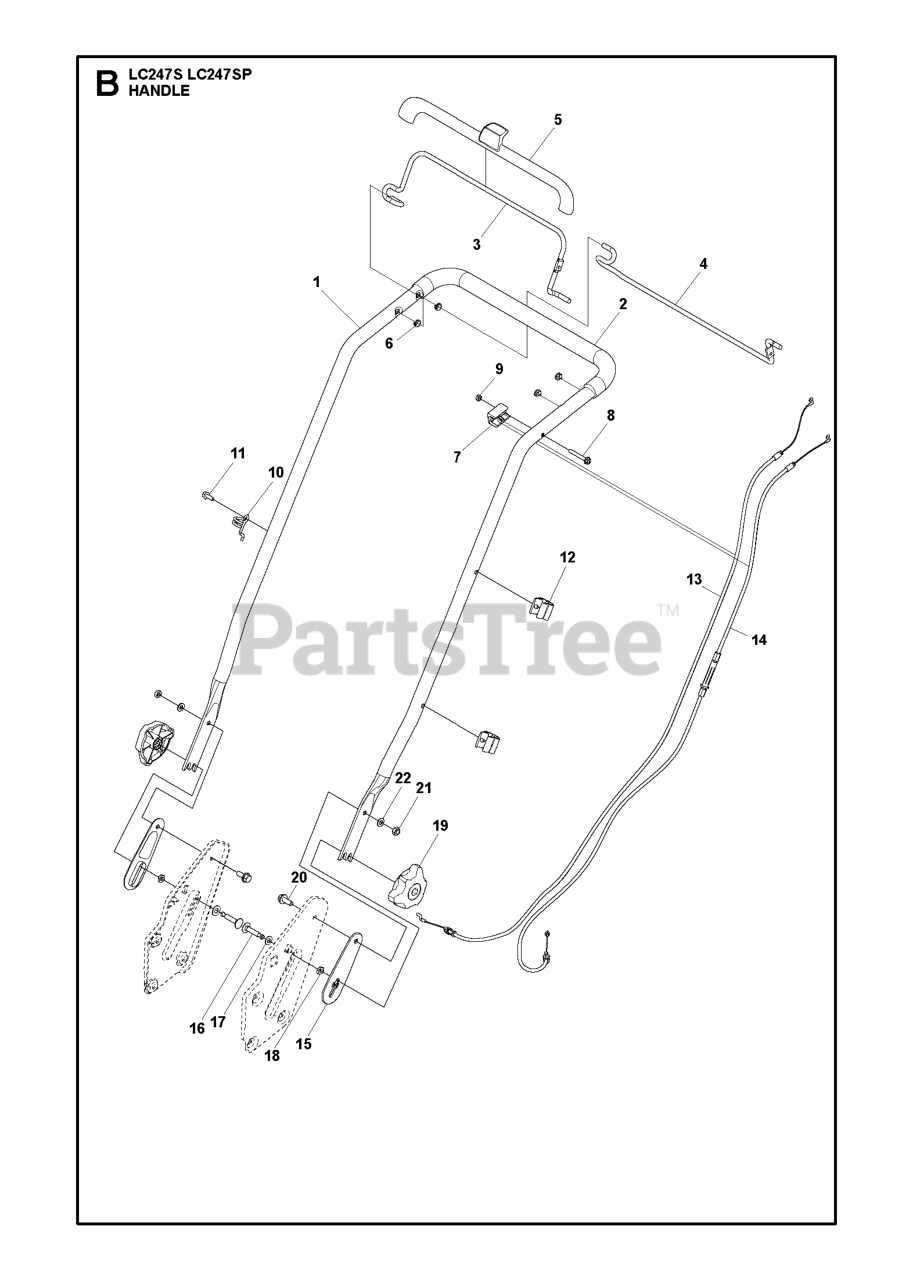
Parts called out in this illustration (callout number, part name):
9	NUT FLANGE - M6
11	SCREW
18	NUT ML6M M8
21	LOCKNUT M8
